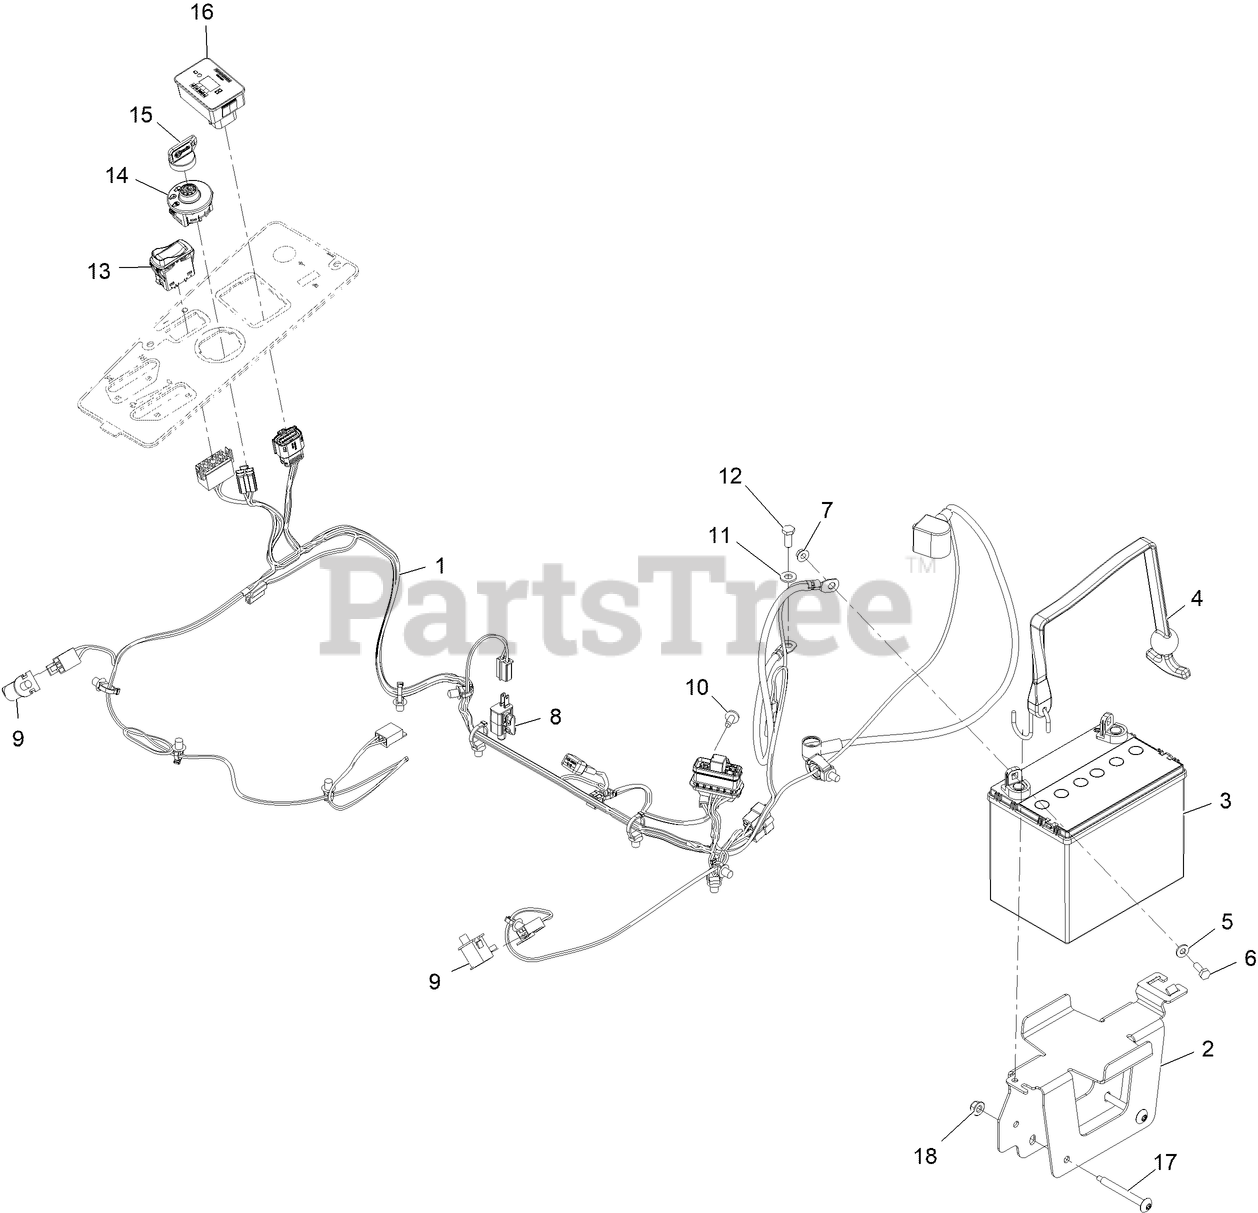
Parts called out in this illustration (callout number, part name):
1	Harness-Main
2	TRAY-BATTERY
3	Battery
4	STRAP, BUNGEE
5	WASHER-FLAT
6	SCREW-HH
9	SWITCH-BAIL
10	SCREW-TORX
11	WASHER-PLAIN
12	SCREW-HH
13	SWITCH-ROCKER, ON-NONE-ON
14	SWITCH-IGNITION
15	KEYS-IGNITION (SPARE PAIR
15	KEY-IGNITION
16	MODULE ASM
17	SCREW-TORX
18	NUT-HF, NI
